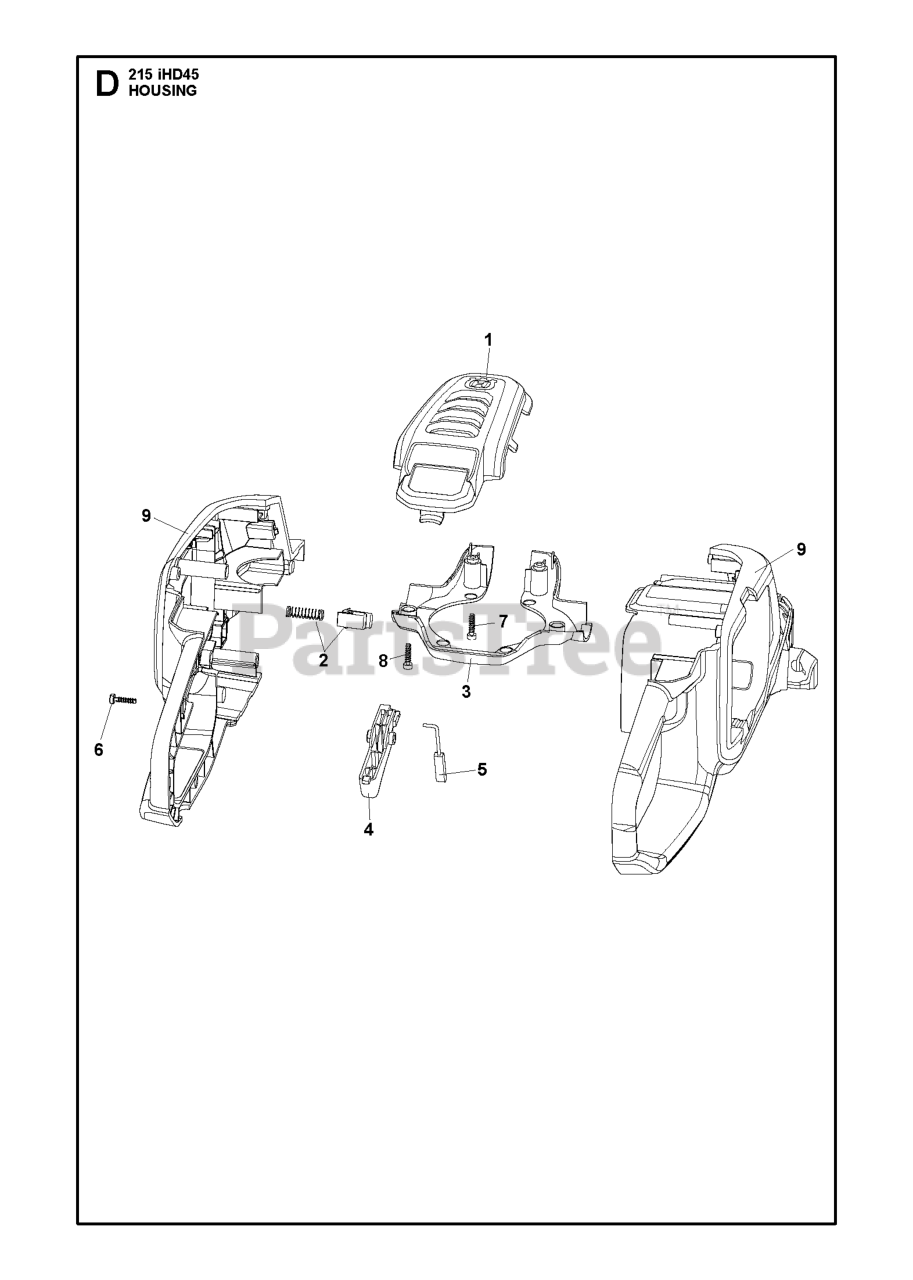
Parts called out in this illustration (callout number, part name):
3	COVER BOTTOM
5	LEVER TRIGGER
6	SCREW ST4X16
